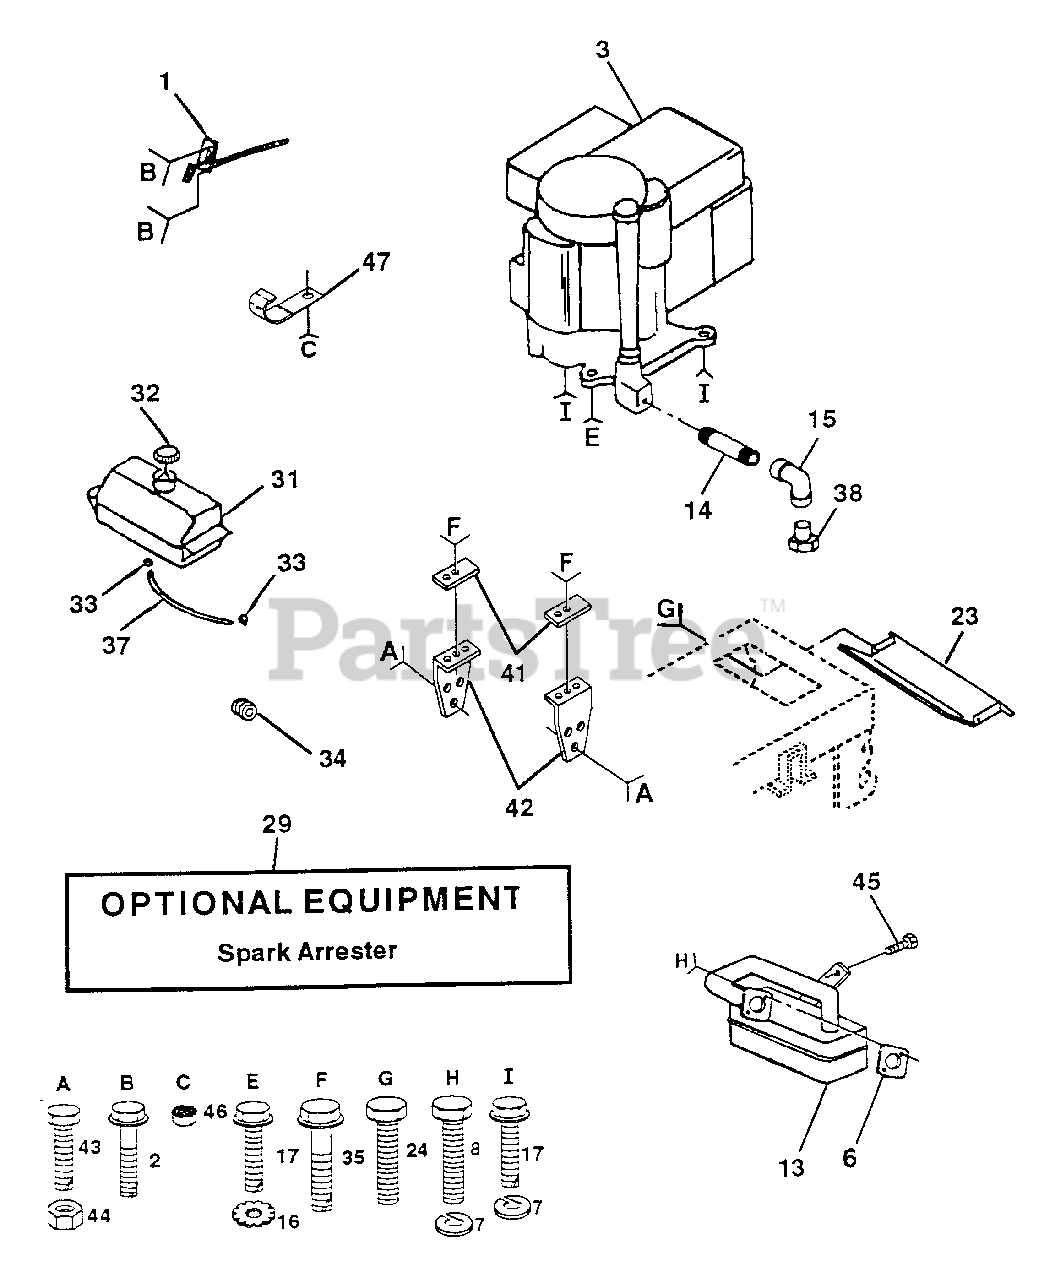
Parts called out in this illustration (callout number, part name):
1	Control Th/ch
2	Screw Hex Thd Cut 1/4-20x5/8 T
6	Gasket, Eng
7	Washer Lock Hvy Hlcl Spr 5/16
8	Bolt, Fin Hex 5/16-18 X 5/8
13	Muffler LT Kohler
14	Nipple Pipe 3/8 Npt X 3-1/2"
15	Elbow Std 900 3/8-18 Npt
16	Washer Lock Ext Tooth 5/16
17	Bolt Hex
23	Shield Heat Browning
24	Screw Hex Thd Cut #10-24unc X 1/2
29	Kit Spark Arrestor
31	Fuel Tank Front 1 25
32	Cap Asm Fuel W/sym Vented
33	Hose Clamp
34	Bushing Snap Nyl Fuel Line
35	Screw Hexwash Thdrol 3/8-16x3/4 Ty-tt
37	Fuel Line
38	Plug Oil Drain
41	Strap Support Fuel Tank
42	Bracket Support Tank Fuel
43	Bolt, Hex 3/8-16unc X 1
44	Nut, Crownlock 3/8-16 Unc
45	Bolt, Hex
46	Nut, Hex Keps 3/8-16
47	Clip Fuel Line
